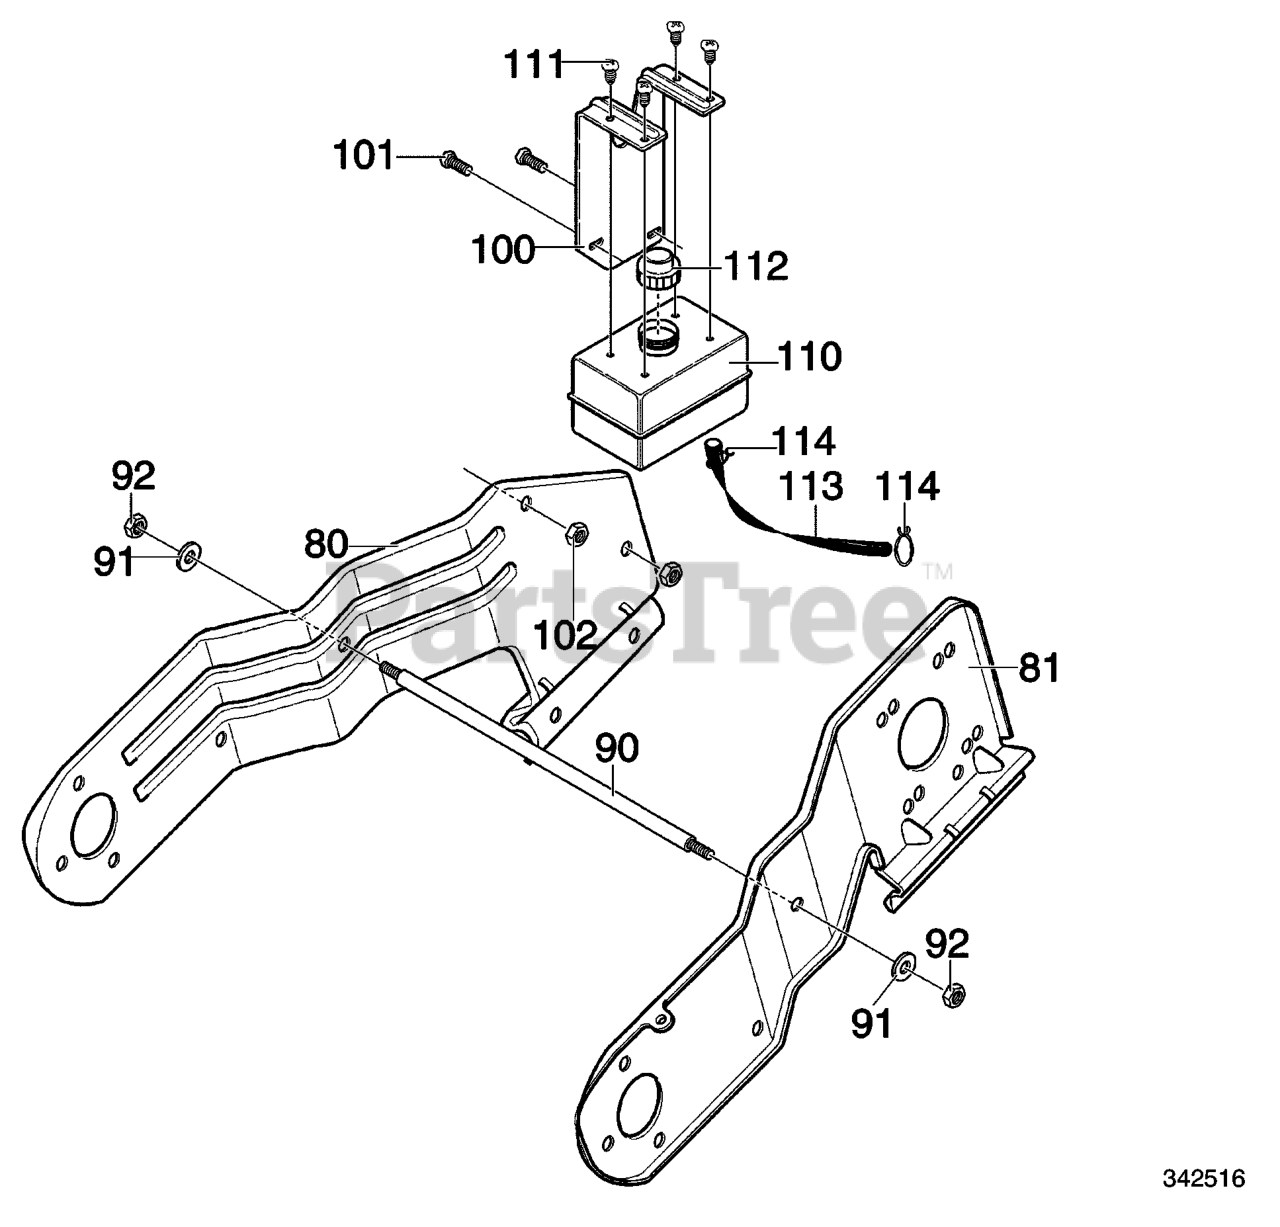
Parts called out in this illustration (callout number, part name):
80	FRAME SIDE SUPPORT RH
81	FRAME SIDE SUPPORT LH
90	ROD, SUPPORT
91	WASHER, HVSPTLK
92	NUT, 3/8-16 REGHEX
100	BRACKET, GAS TANK
101	SCREW, 1/4-20X.75
102	NUT, 1/4-20 YZ
110	TANK, FUEL
111	SCREW, 1/4-14X.88 WAHHTAP
112	CAP, GAS-RED
113	TUBING 11.50 IN.
114	CLAMP, FUEL LINE
